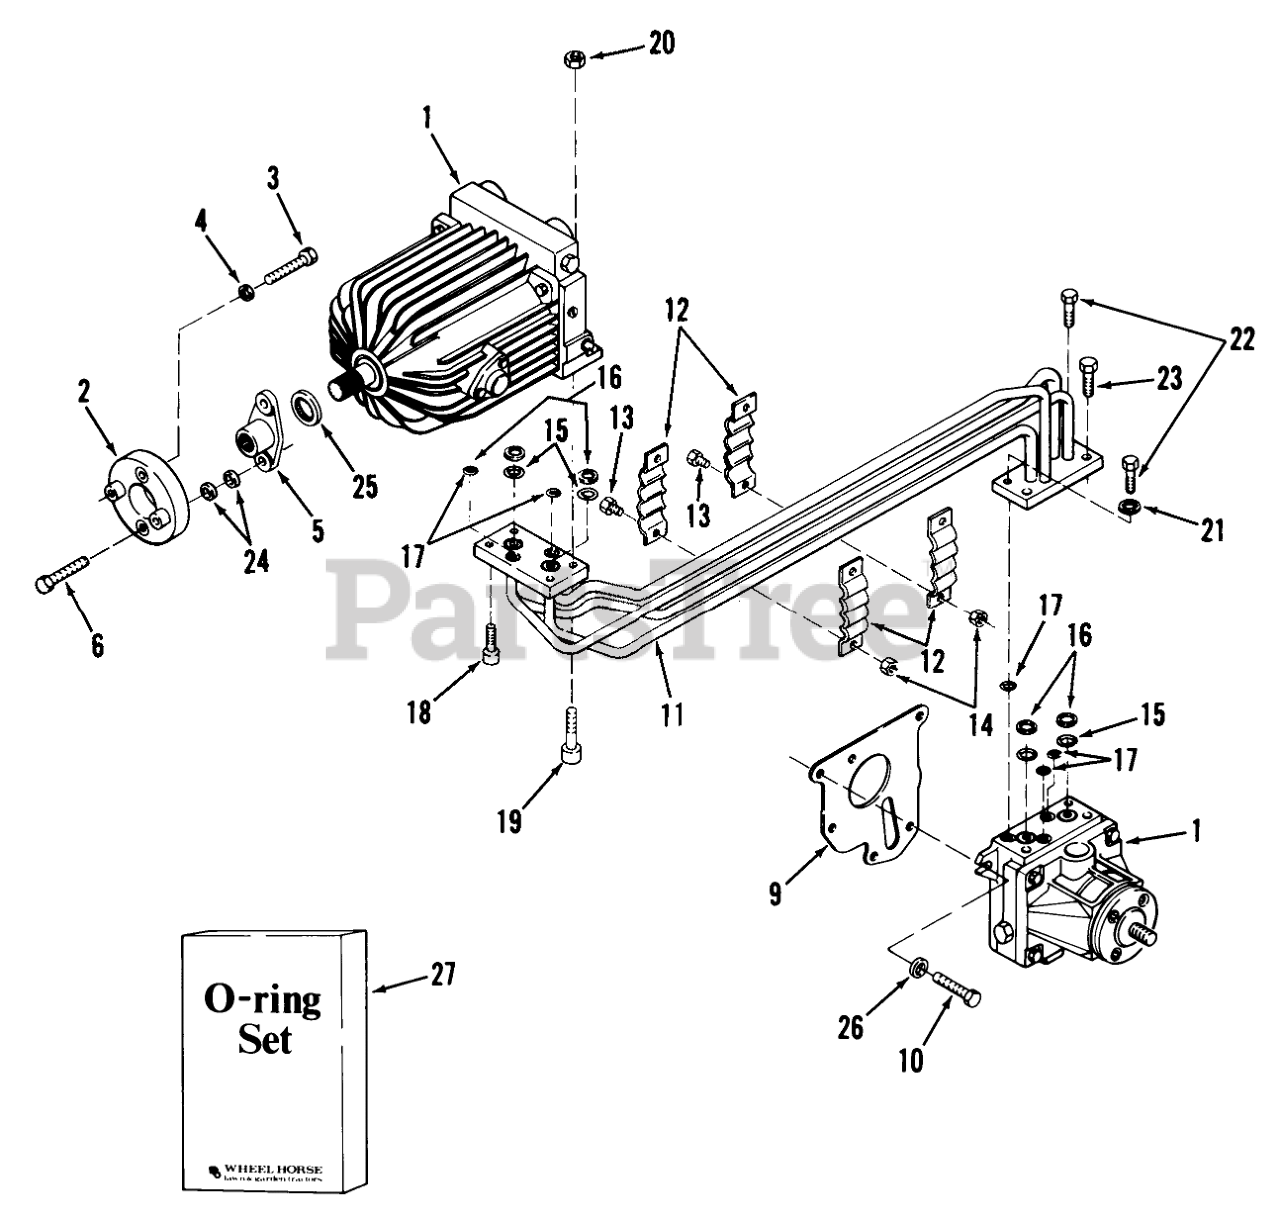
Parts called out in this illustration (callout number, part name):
1	Trans Assembly Piston To Piston-Complete
2	Coupling
3	Bolt 5/16-18 x 2
3	HHCS
4	Lockwasher
5	COUPLING DRIVEN R
6	Bolt
9	GASKET
10	BOLT
11	Manifold, Hydraulic
12	Clamp
13	Bolt
14	Nut
15	O RING
16	RING BACKUP
17	O RING
18	Bolt
19	Screw
20	NUT
21	SEAL-MANIFOLD BOLT
22	Bolt
23	Bolt 3/8-16 X 1
24	WASHER 5/16 SAE
25	WASHER-INT SPLINE
26	Washer
27	O-Ring Kit-S.A. Incs 15, 16, 17 & 21
